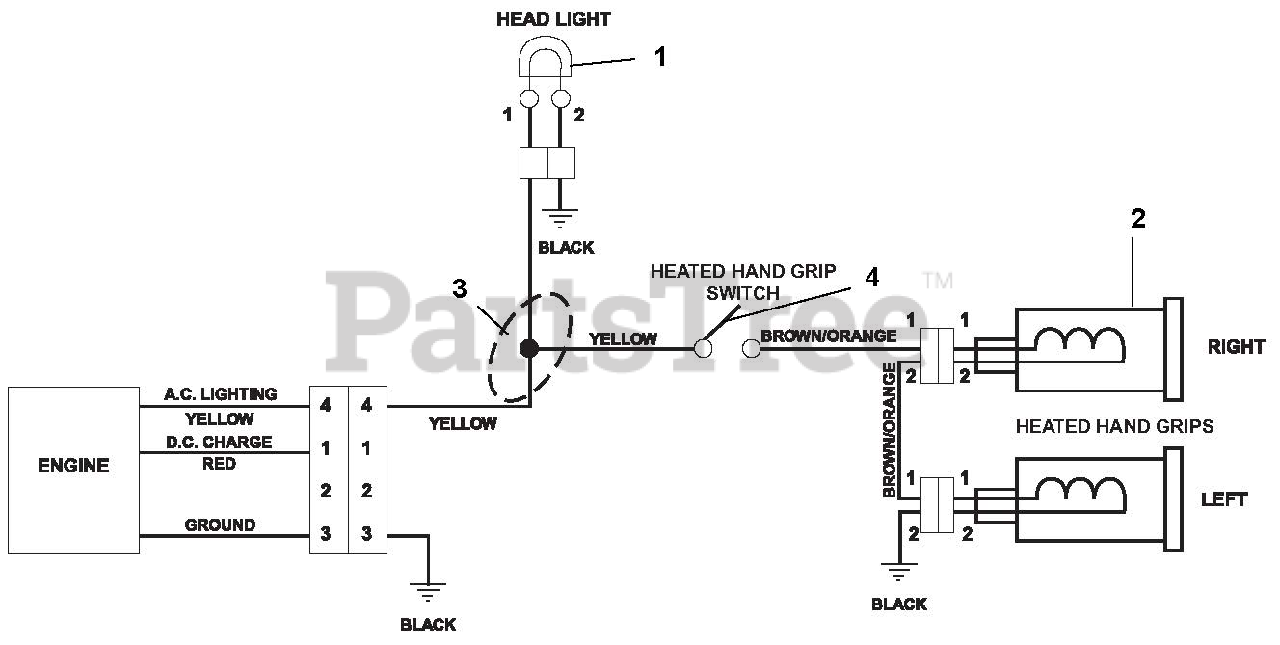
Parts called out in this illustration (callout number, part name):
1	HEADLIGHT ASY, HALO 20W 2SHOT
2	GRIP,HEATED HANDLE-GRAY
3	HARNESS, LIGHT & WARMER
4	SWITCH,ROCKER SPST-ON/OFF
